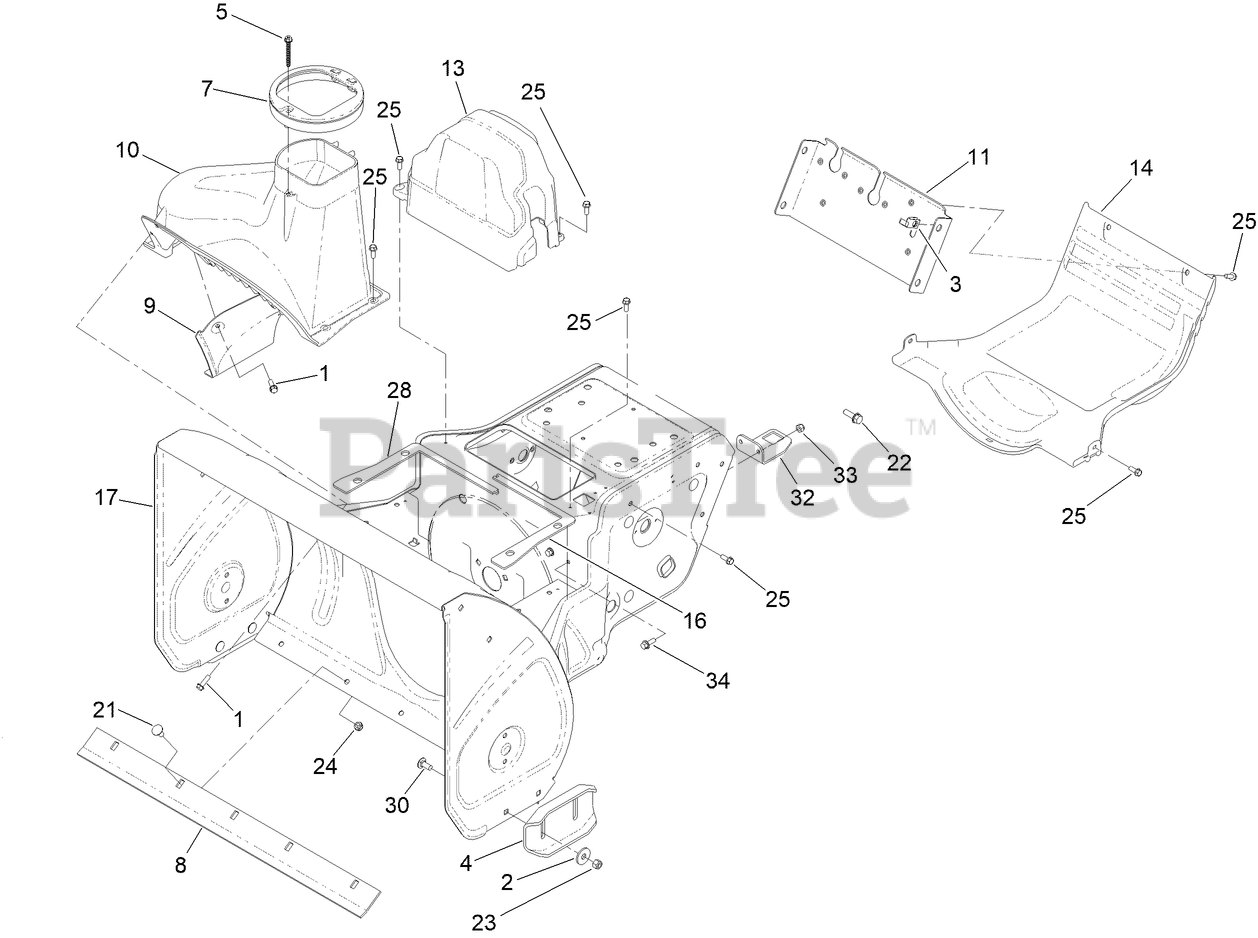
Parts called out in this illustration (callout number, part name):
1	SCREW-HWH
2	WASHER
3	NUT-U
5	SCREW-HWH, PLASTITE
7	GUIDE-CHUTE
8	SCRAPER-26 INCH
9	COVER-LINER
11	BRACE-FRAME
13	COVER-BELT
14	COVER-LOWER
16	SEAL-HOUSING, LH
17	FRAME ASM
21	SCREW-CARR
22	SCREW-HHF
23	NUT-LOCK, NI
24	NUT-LOCK, NI
25	SCREW-HWH
28	SEAL-HOUSING, RH
30	SCREW-CARR
32	BRACKET-POST, CHUTE
33	SCREW-HHF
34	NUT-HEX
